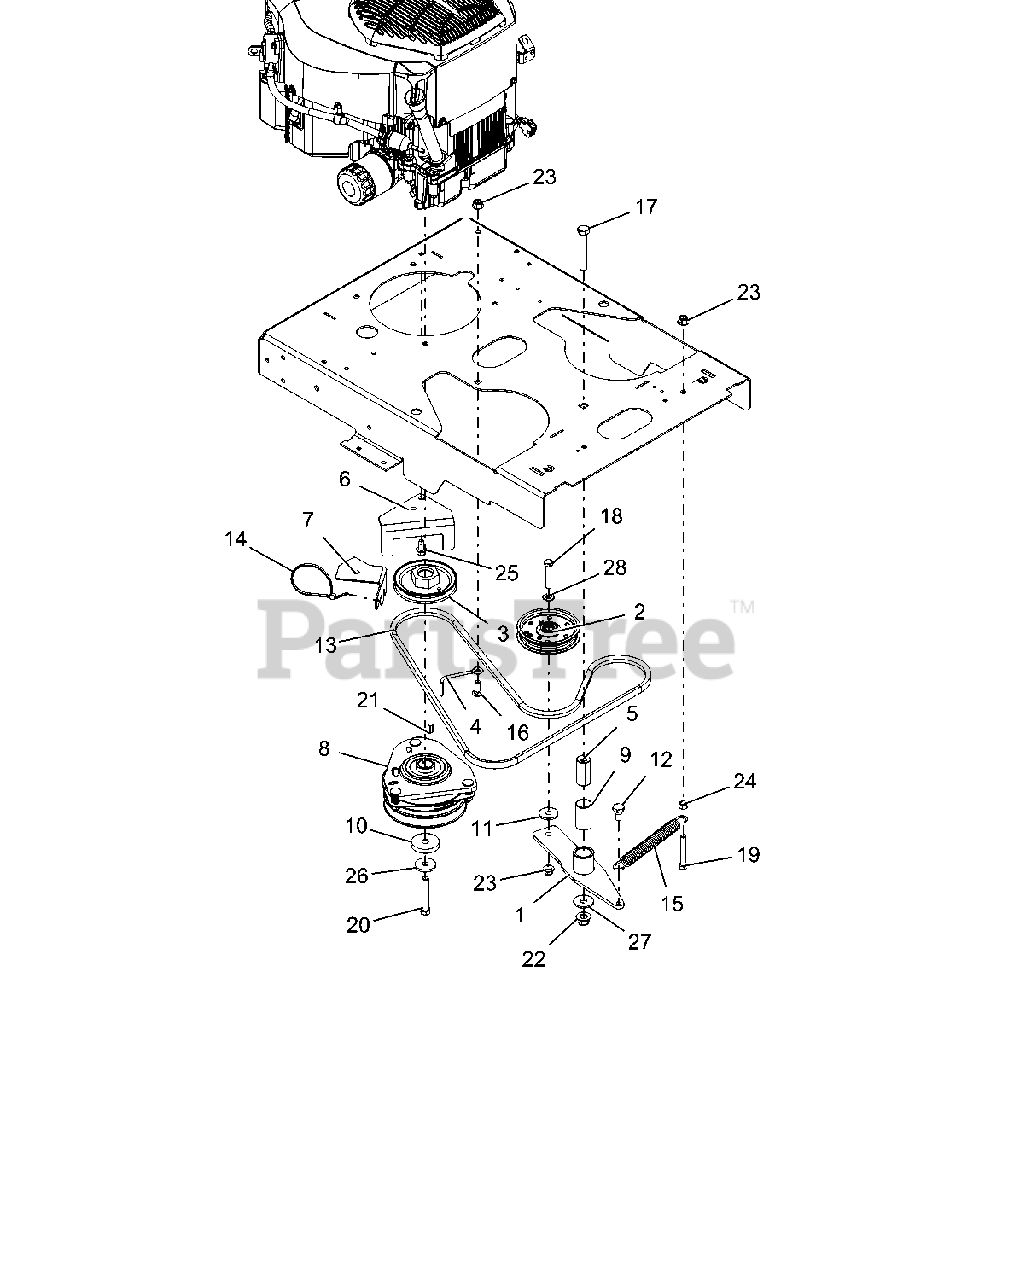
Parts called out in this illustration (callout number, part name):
1	HYDRO DRIVE IDLER ARM WMT -BLK
2	ASM, 4" IDLER (.75 WIDE)
3	PULLEY-4.50OD X 1.002 ENGINE
4	BELT FINGER
5	BSHG, SPCR .502X.997X2.03 PM
6	ANCHOR - OGURA CLUTCH - HD
7	GUARD, HD CLUTCH WIRE
8	CLUTCH, OGURA GT1A
9	BSHG, 1.00 X 1.125 X 1.937
10	SPACER, .474/.459X2.00X.350
11	WSHR-FL-STL .406X1.375X.135 YZ
12	BLT,SHLDR EP .38-16X.30 HEX YZ
13	V-BELT, 4L-WRAPPED
14	CABLE TIE LG 5-1/2
15	SPRING, EXTENSION
16	@BLT-RDHDSQNK .38-16X1.00 G5YZ
17	@BLT-HEX .50-13X3.25 GR5 YWZC
18	@BLT-HEX .38-16X2.00 GR5 YWZC
19	@BLT-HEX .38-16X2.50 GR5 YWZC
20	BLT-HEX .44-20X2.75 G8YZNYTORQ
21	KEY-SQ .25X.625X.25 SAE 8630
22	@NUT-LK-NYL-FLG .50-13 YWZC
23	@NUT-LK-NYL-FLG .38-16 YWZC
24	@NUT-HEX .38-16 YWZC
25	@SCR-TAP .38-16X.75 HWH TR YWZ
26	WASHER, 7/16" SPRING DISK
27	WSHR-FL-STL.511X1.441X.125 YWZ
28	@WSHR-FL-STL.406X.812X.065 YWZ
